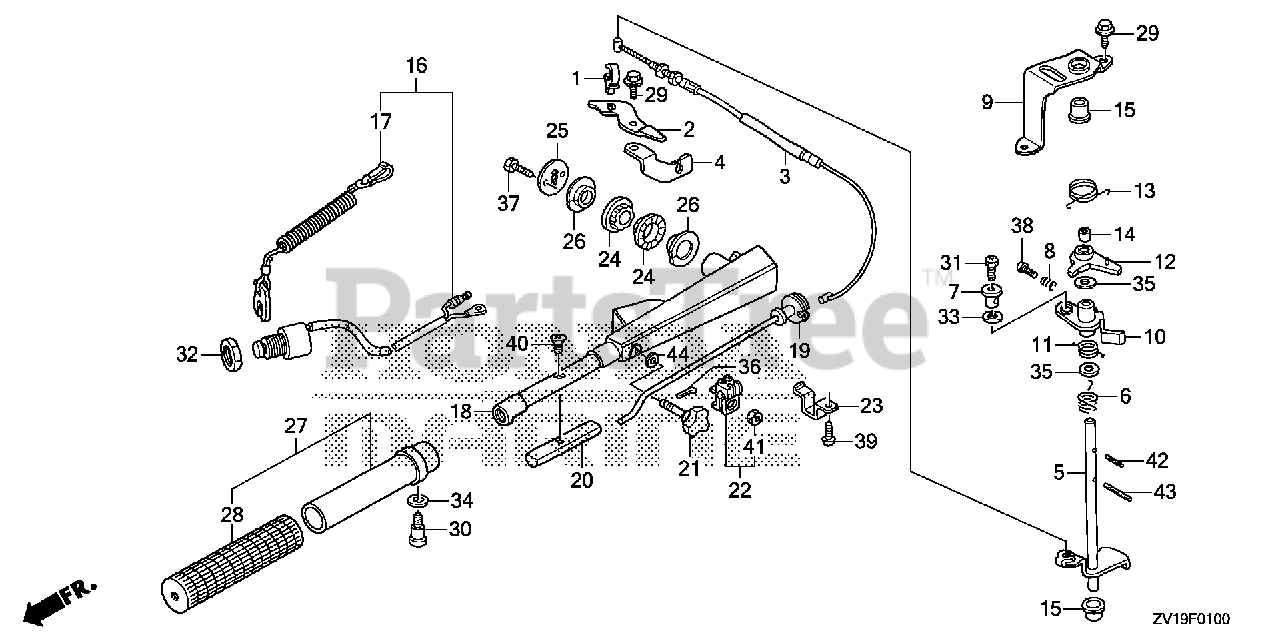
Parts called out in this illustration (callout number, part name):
1	CLAMP, CARBURETOR SOLENOID WIRE HARNESS
2	STAY, FUEL TUBE
3	CABLE, THROTTLE
4	HOLDER, CABLE
5	SHAFT, THROTTLE
6	SPRING, THROTTLE ARM
7	HOLDER, THROTTLE ROD
8	SPRING, THROTTLE ADJUSTING
9	STAY, THROTTLE SHAFT
10	LINK, THROTTLE
11	SPRING, RETURN
12	POWL, NEUTRAL START
13	SPRING, POWL
14	COLLAR, POWL
15	BUSH, SHAFT
16	SWITCH ASSY., EMERGENCY STOP
17	WIRE, EMERGENCY (SINGLE) (DUAL)
18	HANDLEBAR *NHB14M* (AQUA MARINE SILVER METALLIC)
19	REEL, THROTTLE
20	WEIGHT, HANDLEBAR
21	BOLT, FRICTION
22	BLOCK, THROTTLE FRICTION
23	STAY A, THROTTLE REEL
24	RUBBER, HANDLE MOUNTING
25	PLATE, HANDLEBAR
26	COLLAR, HANDLEBAR
27	PIPE, GRIP
28	RUBBER, GRIP
29	BOLT, FLANGE (6X14) (CT200)
30	BOLT, PIPE GRIP
31	BOLT, RECESSED (5X8)
32	NUT, HEX. (16MM) DUAL QTY = (2) (SINGLE)
33	WASHER, NYLON (9MM)
34	WASHER (7.5MM)
35	WASHER, PLAIN (10MM)
36	PIN, SPLIT (2.0)
37	BOLT, HEX. (6X16)
38	SCREW, PAN (4X20) (NOT AVAILABLE)
39	SCREW, PAN (5X12)
40	SCREW, OVAL (6X12)
41	NUT, HEX. (6MM)
42	PIN, SPRING (3X18)
43	PIN, SPRING (3X32)
44	WASHER, PLAIN (6MM) Use from Frame SN 4800713.
